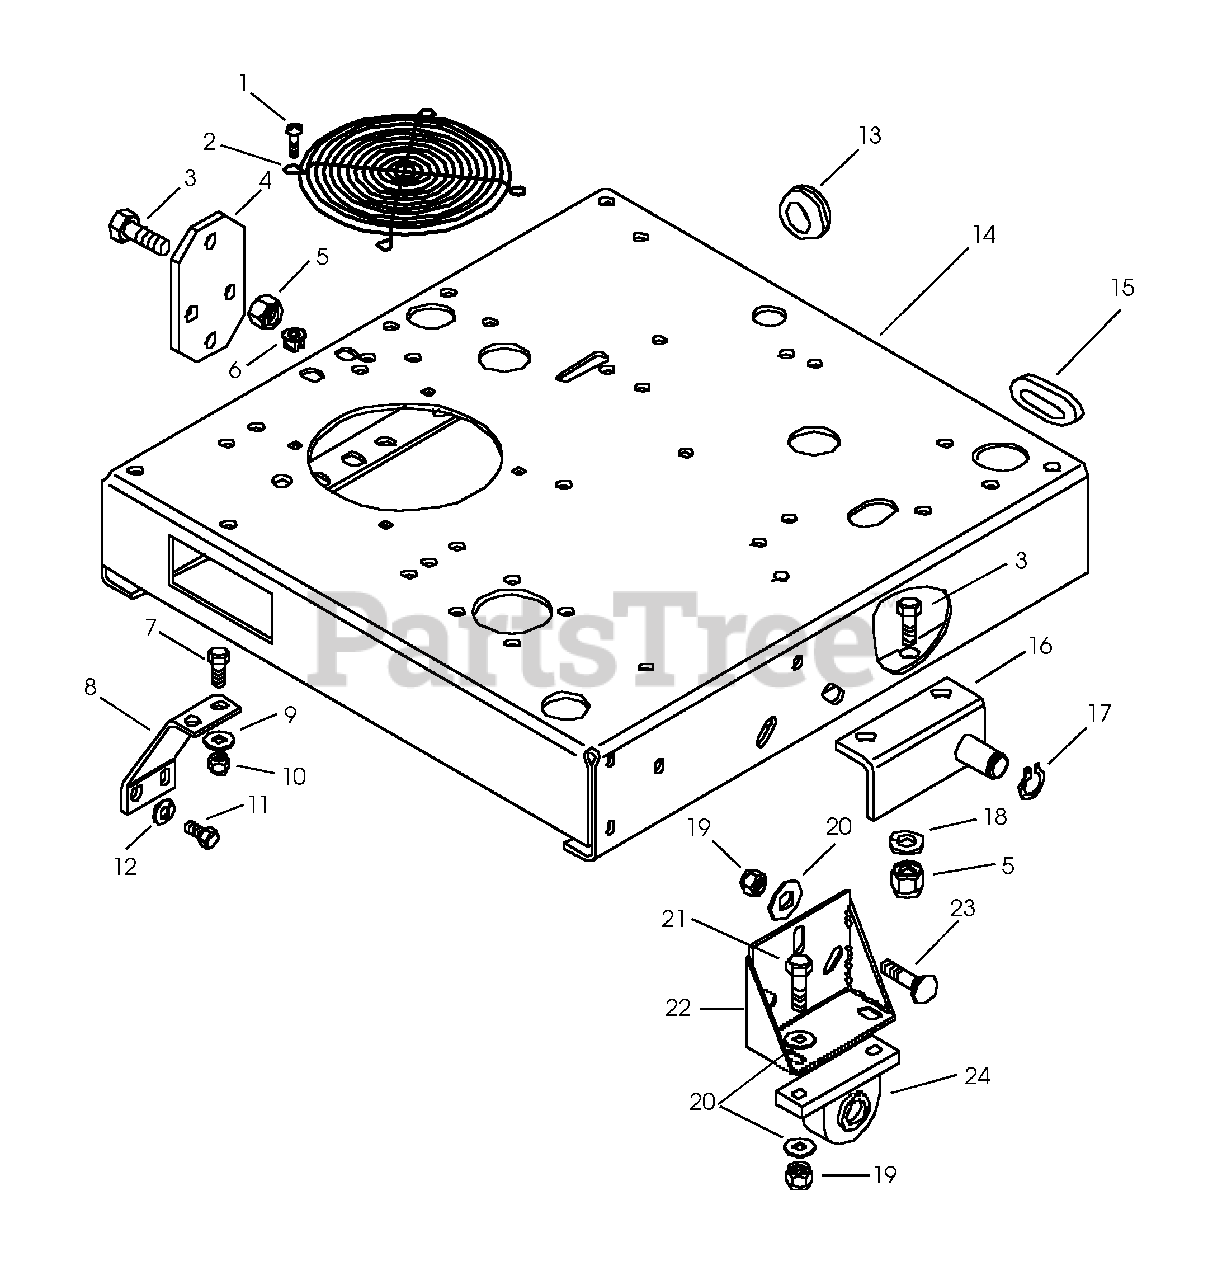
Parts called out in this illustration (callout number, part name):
1	Screw-Tapping .25-20 x .50
2	Guard Fan
3	Bolt-Hex .50-13 x 1.50 Grade 5
4	Plate
5	Nut-Locking-Center .50-13
6	Grommet-Plastic
7	Bolt-Hex .38-16 x 1.00 Grade 5
8	Bracket-Transaxle Support
9	Washer-Flat-Steel .344 x .688 x .065
10	Nut-Locking-Center .38-18
11	Bolt-Hex .31-18 x .75 Grade 5
12	Washer-Lock .31 x .078
13	Grommet 1.50 x 1.75 x 2.12
14	Weldment-Frame
15	Grommet .63 x .687 x 1.25
16	Weldment-Pivot Left Hand
16	Weldment-Pivot Right Hand
17	Ring-Retaining-External .689 x .077
18	Washer-Lock .50 x .125
19	Nut-Locking-Center .38-16
20	Washer-Flat-Steel .406 x .812 x .065
21	Bolt-Hex .38-16 x 1.50 Grade 5
22	Weldment-Axle Support
23	Bolt-Round Head Square Neck .38-16 x 1.00
24	Bearing-Pillow Block 1.0 x 2.688 x 6.188
